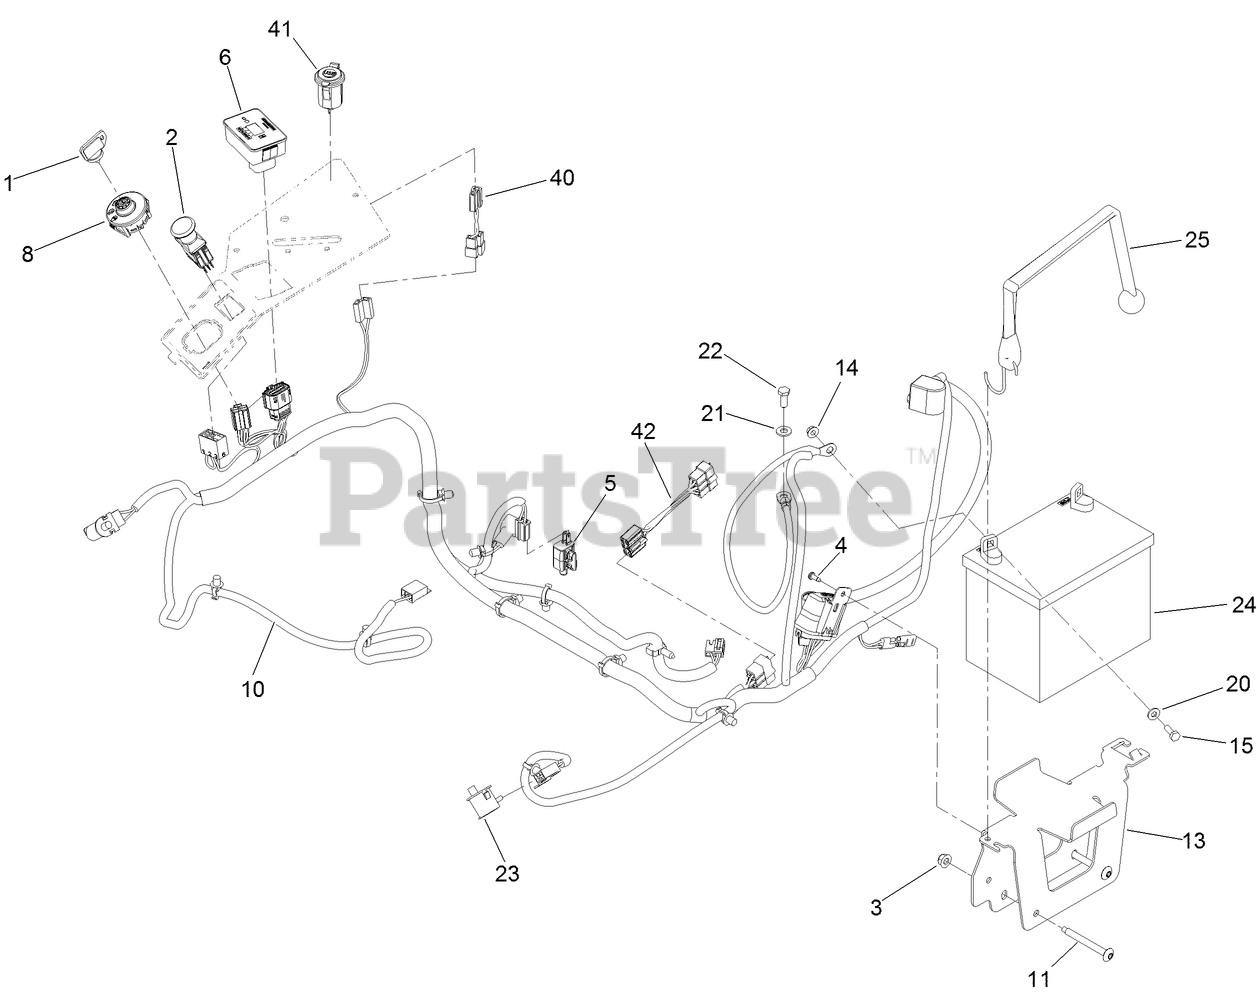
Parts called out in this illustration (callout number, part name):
1	KEY-IGNITION
2	SWITCH-PTO
3	NUT-HF, NI
4	SCREW-FORMING, THREAD
5	SWITCH
6	MODULE ASM
8	SWITCH-IGNITION
10	HARNESS-WIRE
11	SCREW-TORX
13	TRAY-BATTERY
14	NUT-HF
15	SCREW-HH
20	WASHER-FLAT
21	WASHER-PLAIN
22	SCREW-HH
23	SWITCH-BAIL
24	BATTERY
25	STRAP-BUNGEE
40	HARNESS-WIRE, USB KIT
41	PORT-POWER, USB
42	Harness-Wire Jumper
